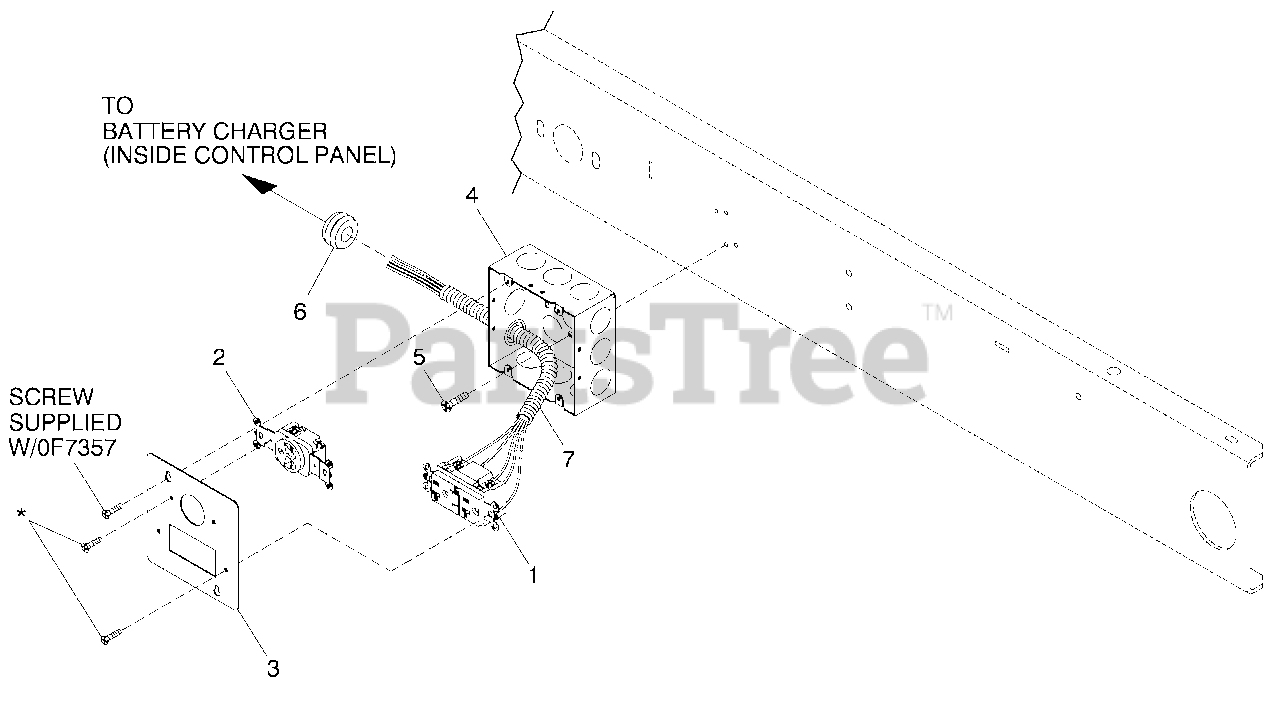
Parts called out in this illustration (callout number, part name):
1	OUTLET 20A GFCI
2	OUTLET 15A 250V NEMA 6-15R IVY
3	BOX SQUARE 4-11/16 W/KNO'S
4	SCREW HHTT #10-24 X 3/8 CZ
5	COVER DUAL RECEPT 120/240
6	GROMMET .87 X .25 X .62
7	HARN ALT CON BOX 1PH QT
